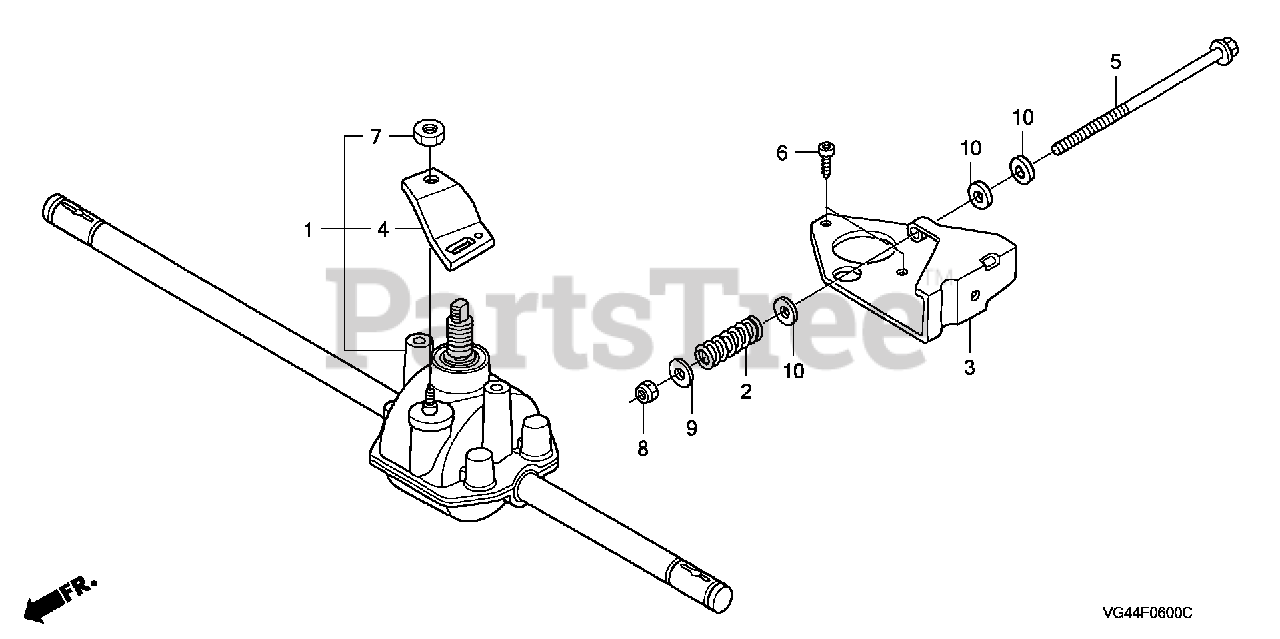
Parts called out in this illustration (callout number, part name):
1	TRANSMISSION ASSY.
2	SPRING, BELT TENSIONER
3	HOLDER, WIRE
4	ARM, CLUTCH
5	BOLT, FLANGE (6X140)
6	SCREW, TAPPING (1/4")
8	NUT, NYLON LOCK (6MM)
9	WASHER, PLAIN (6MM)
10	WASHER, PLAIN (8MM)
